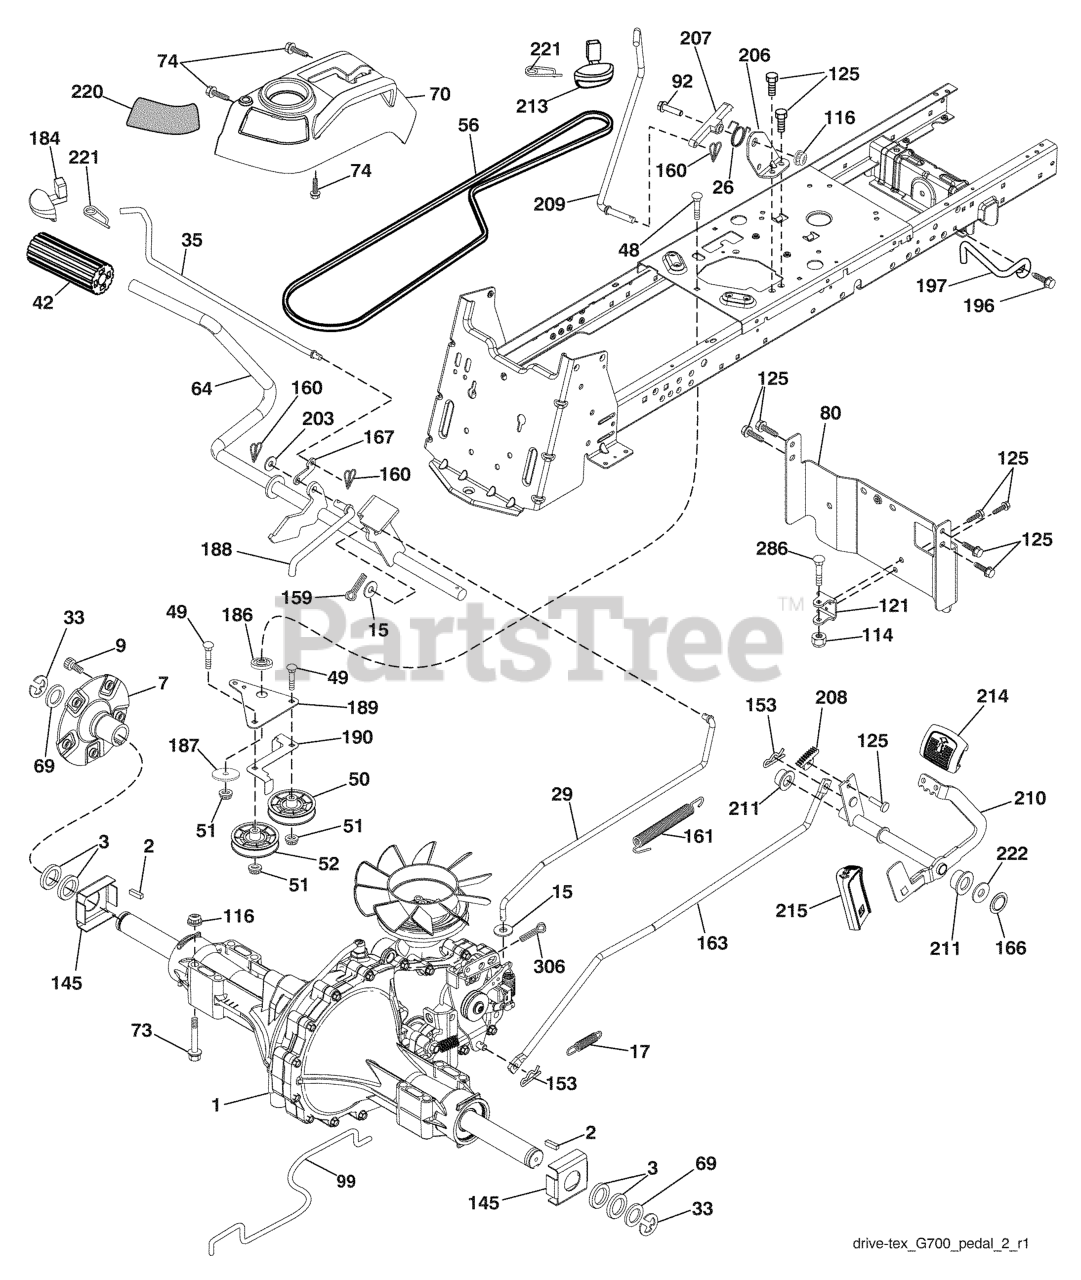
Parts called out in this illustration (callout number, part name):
2	KEY 1/4 X 2.5
7	HUB.ASM.WHEEL.REAR.23"TEX
9	HUB BOLT
15	WASHER
17	SPRING.BRAKE.HG3000/3500
26	SPRING.RETURN.CRUISE
33	E RING HYT
35	ROD.BRAKE.PARKING.GT.H
42	PEDAL COVER T
48	BOLT.3/8-16X1.50
50	IDLER.FLAT.910.OFFSET
51	NUT LOCK FLG 3/8-16 UNC
52	IDLER.V-GROOVE.910.OFFSET
56	V-BELT.GROUND.DRIVE.
64	SHAFT.ASM.PEDAL.BRK.CNTR
70	RP CONSOLE.ASM.PCH.W/TB
73	BOLT HEX FLGHD 5/16-18X3 GR. 5
74	SCREW.HI-LO.CONSOLE
80	STRAP.TORQUE.YT.G700
92	BOLT
99	SPRING.BYPASS.YT.G700
114	NUT.71038.31-18.HEX.NYLOCK
116	NUT LOCK HEX FLANGE 5/16-18
121	BRACKET STRAP TORQUE
125	SCREW
145	WASHER.AXLE.FLANGE.HG-3000
153	RETAINER M
159	COTTER PIN
160	RETAINER CLIP
161	SPRING, RETURN LT
163	ROD PEDAL CONTROL
166	NUT.PUSH.625.2006
167	LATCH.BRAKE.SPRING
184	HANDLE.PARKG.BRK.HUSQ X667
186	SPACER.RETAINER
187	WASHER 12/32X2X10GA
188	RP.LINK.CLUTCH.GROUND.DRIVE
189	BELLCRANK.GROUND.DRIVE.TRAPPED
190	KEEPER BELLCRANK ROUND DRIVE
196	SCREW 3/8-16X1
197	BRKT.ANIT-ROTATION.CLUTCH
203	WASHER
206	BRKT.MOUNT.LATCH.CRUIS
207	LATCH.CONTROL.CRUISE
208	GEAR.SECTOR.CONTROL.CR
209	ROD.CONTROL.CRUISE.GT.
210	ROCKER.ASM.PEDAL.CONTR
211	BEARING.NYLON
213	KNOB.CONTROL.CRUSIE.HU
214	PEDAL.FORWARD.HUSQVARNA.DEALER
215	PEDAL.REVERSE.TEX.GT.4
220	REFLECTOR.RH.TEX GT
221	RETAINER.SPRING.CLIP.H
222	WASHER 21/32 X 1-1/4 X 10 GA.
286	Bolt 5/16-18 x 2.75
306	PIN COTTER
